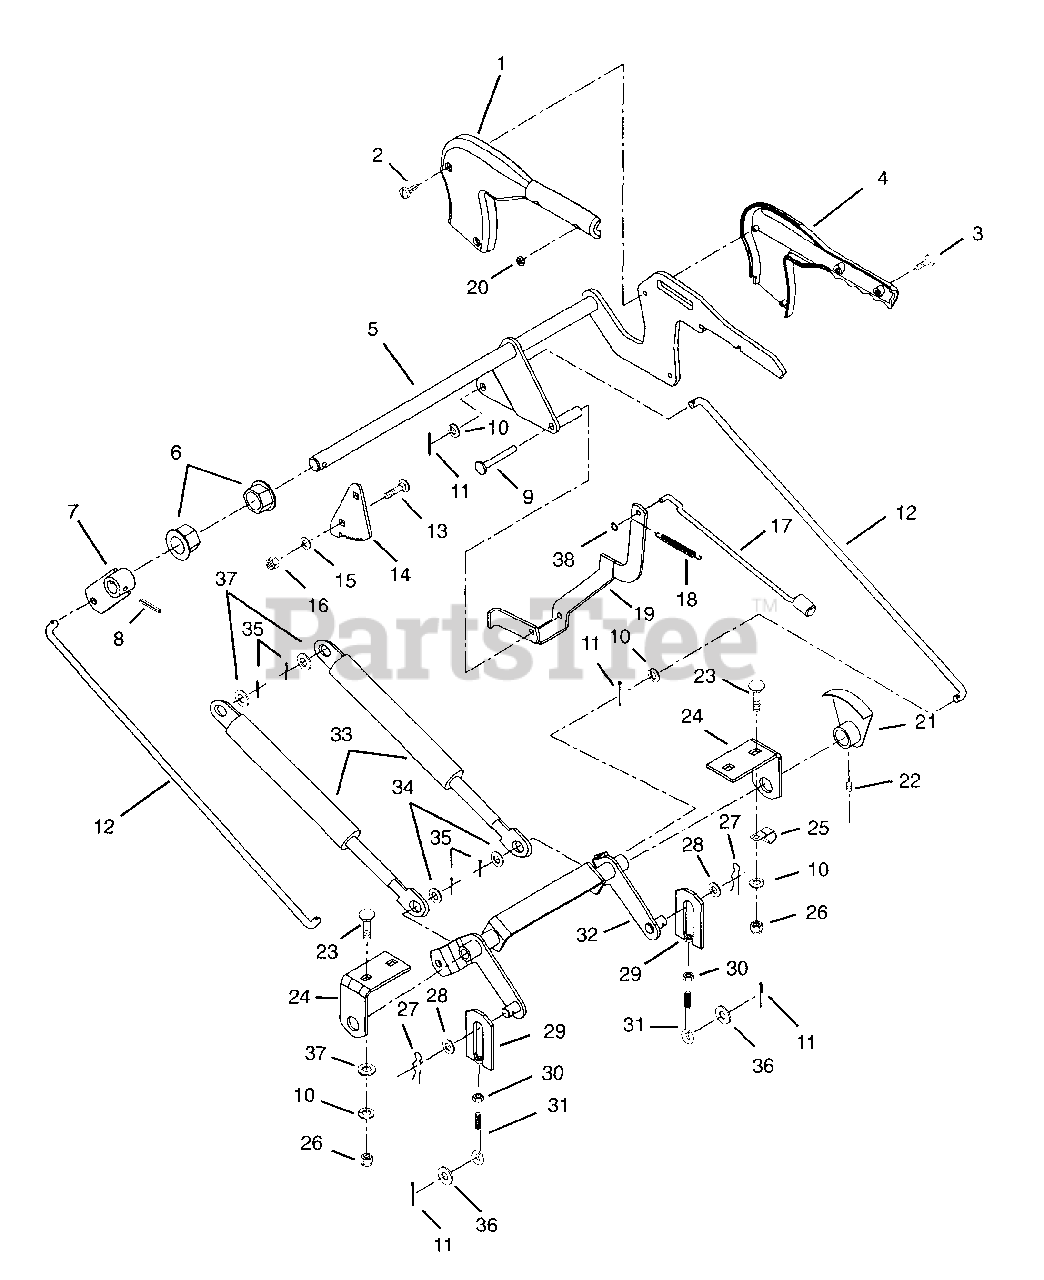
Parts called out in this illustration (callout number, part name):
1	COVER - LIFT RH
2	SCR-TAP 10-16X1.125HI-LOTPHBL
3	@SCR-MCH 10-24X.75 HWH YWZC
4	COVER - LIFT LH
5	LEVER - LIFT
6	BSHG-FLG .750X.873HEXX.53X1.18
7	ARM, LIFT
8	PIN-GRV .250X1.25 TP A
9	PIN, PIVOT .312 X 2.56
10	@WSHR-LK .38X.094 REG YWZC
11	@PIN-CTR .12X1.00 EXTPRSQCT YZ
12	LINK, LIFT
13	@BLT-RDHDSQNK .31-18X.75 G5YZ
14	QUADRANT - LIFT
15	WSHR-FL-STL .323X.625X.062 YWZ
16	@NUT-LK-CTR .31-18 YWZC
17	PIN - LIFT
18	SG-TENS .048X.44X2.25 WLD 9
19	LEVER - DETENT
20	@NUT-LK-NYL 10-24 W/INSRT YWZC
21	INDICATOR - DECK HEIGHT
22	SCR-SET .25-20X.25 SKHCUP OH
23	BLT-RHHDSQSHNK .38-16X.75 G2YZ
24	BRACKET, CENTER LIFT
25	J-CLAMP
26	@NUT-HEX .38-16 YWZC
27	PIN-HAIR-EXT .12X.31X2.37 YWZC
28	@WSHR-FL-STL.531X1.06X.095YWZC
29	LINK, ADJUSTMENT
30	NUT-HEX-JAM .375-16 YWZC
31	EYE BOLT - .375-16 X 3.00 ZC
32	LEVER, CENTER LIFT
33	SG-GAS COMP .315X.75X10.00 120
34	@WSHR-FL-STL.38X.875X.083 YWZC
35	@PIN-CTR .12X.75 EXTPRSQCT YWZ
36	@WSHR-FL-STL.656X1.31X.095 YWZ
37	@WSHR-FL-STL.406X.812X.065 YWZ
38	RG-RTNG-EXT .250X.010
